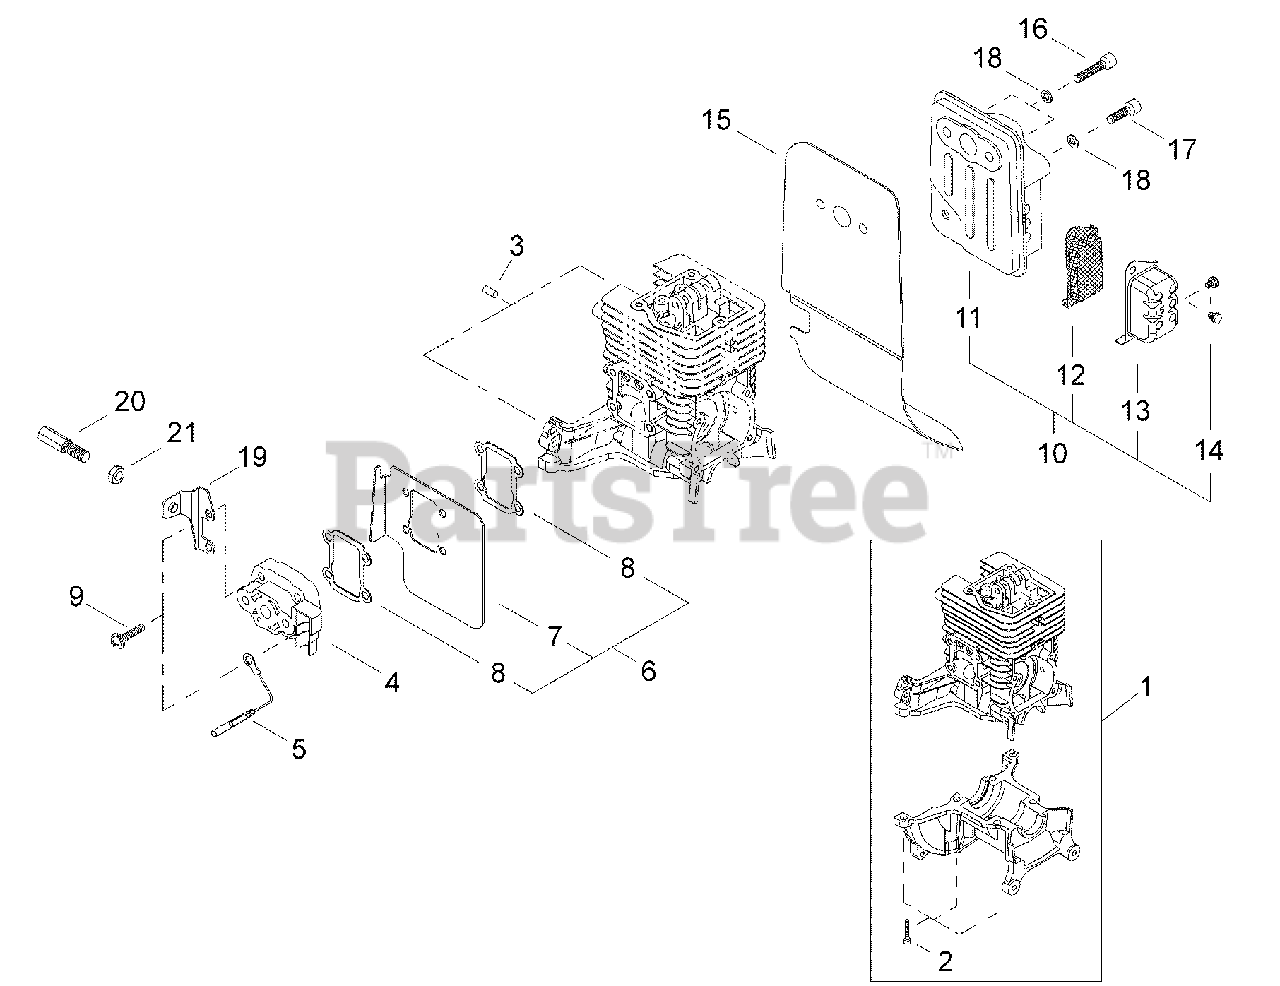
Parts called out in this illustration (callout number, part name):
1	CYLINDER & CRANKCASE ASSY
2	BOLT 5×16
3	PIN, LOCATING Ø4×8
4	INSULATOR WITH REED VALVE
5	LEAD - GROUND L= 110 MM
6	SHIELD ASSY, INTAKE HEAT
7	HEAT SHIELD, INTAKE
8	GASKET, EXHAUST
9	SCREW M5×22
10	MUFFLER ASSY
11	MUFFLER
12	SCREEN, SPARK ARRESTER
13	GUIDE, EXHAUST
14	SCREW M4×6
15	HEAT SHIELD, EXHAUST
16	BOLT M5×25
17	BOLT 5×16
18	WASHER, FLAT 5.5×10×0.8
19	BRACKET, THROTTLE CABLE
20	ADJUSTER, THROTTLE CABLE
21	NUT, ADJUSTER LOCK M6
